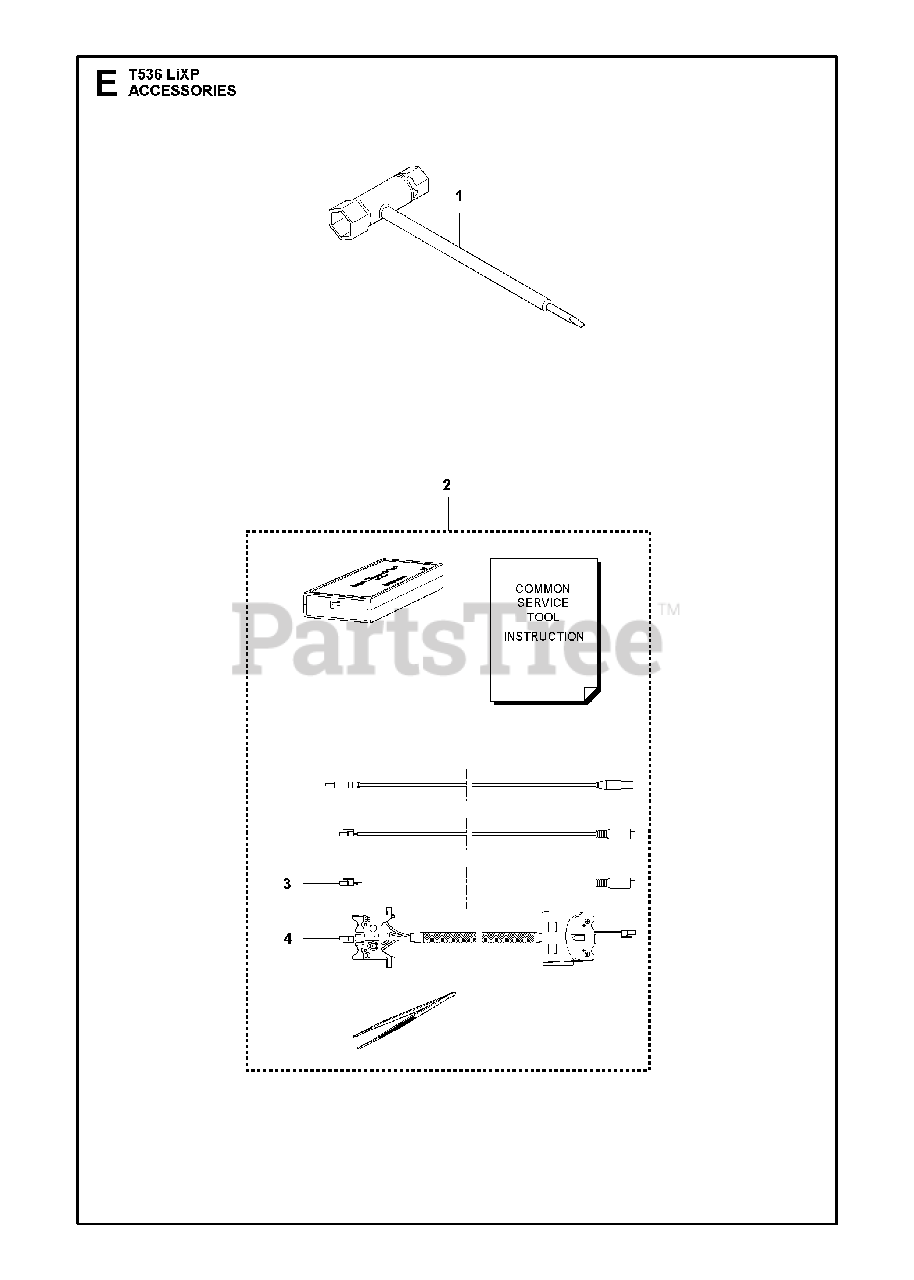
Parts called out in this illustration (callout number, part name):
1	COMBI TOOL
2	DIAGNOSTIC TOOL KIT
3	CABLE ASSY
4	WIRING ASSY
